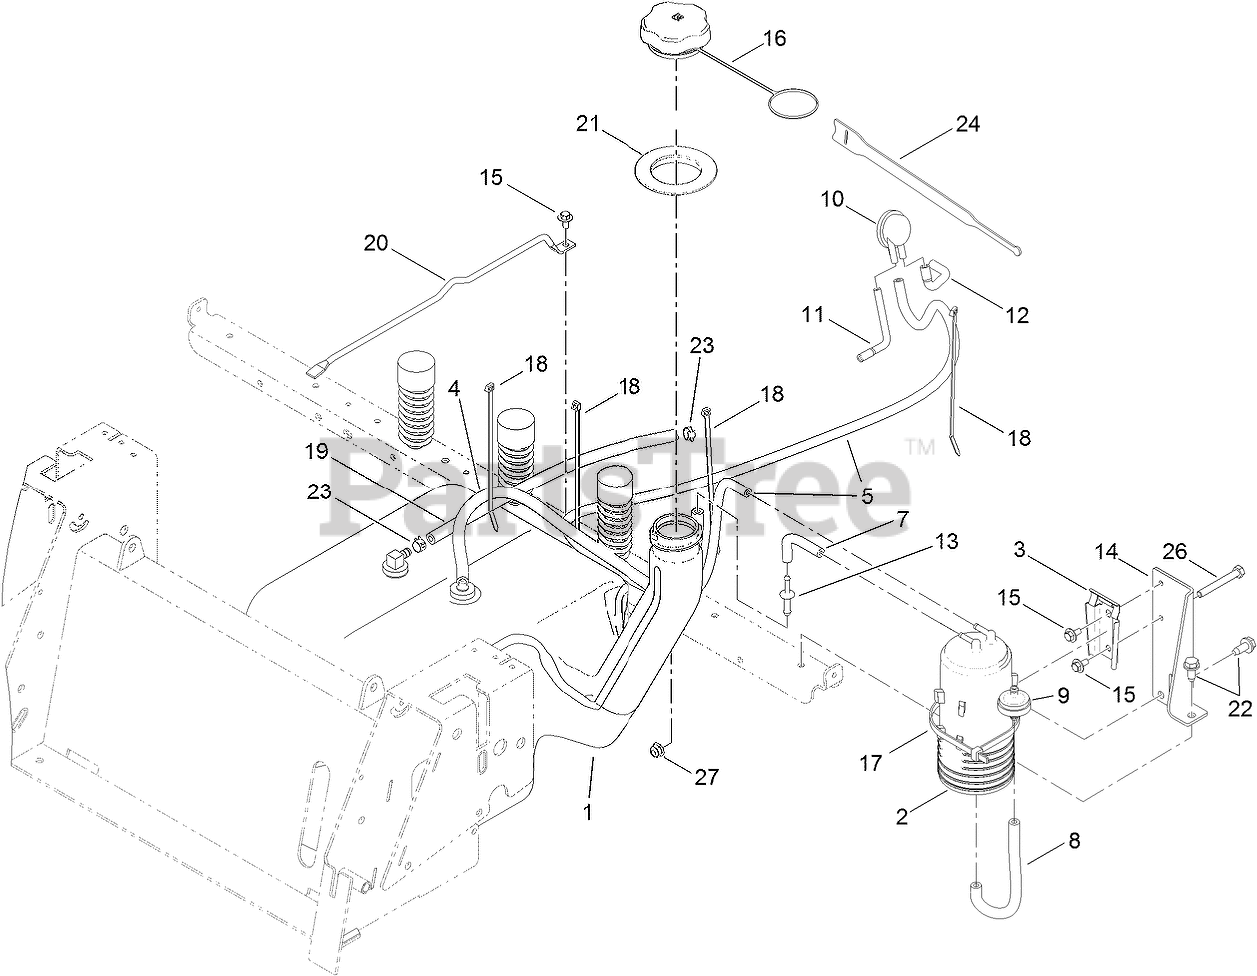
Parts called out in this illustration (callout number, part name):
1	FUEL TANK ASM
2	CANISTER-CARBON, 800CC
3	BRACKET-CANISTER, CARBON
4	HOSE-FUEL
5	HOSE-FUEL
7	HOSE-FUEL
8	HOSE-FUEL
9	FILTER-FUEL, INLINE
10	VALVE-CONTROL, VACUUM
11	HOSE-VENT, FORMED
12	HOSE-VENT, FORMED
13	ADAPTER-ORIFICE
14	BRACKET-CANISTER
15	SCREW-HHFTF
16	CAP-FUEL
17	TIE-CABLE
18	TIE-CABLE
19	HOSE-FUEL
20	ROD-TANK, GAS
21	SEAL-TANK
22	SCREW-HWHTF
23	CLAMP-HOSE
24	STRAP-VELCRO, CABLE TIE
26	SCREW-HH
27	NUT-HF, NI
